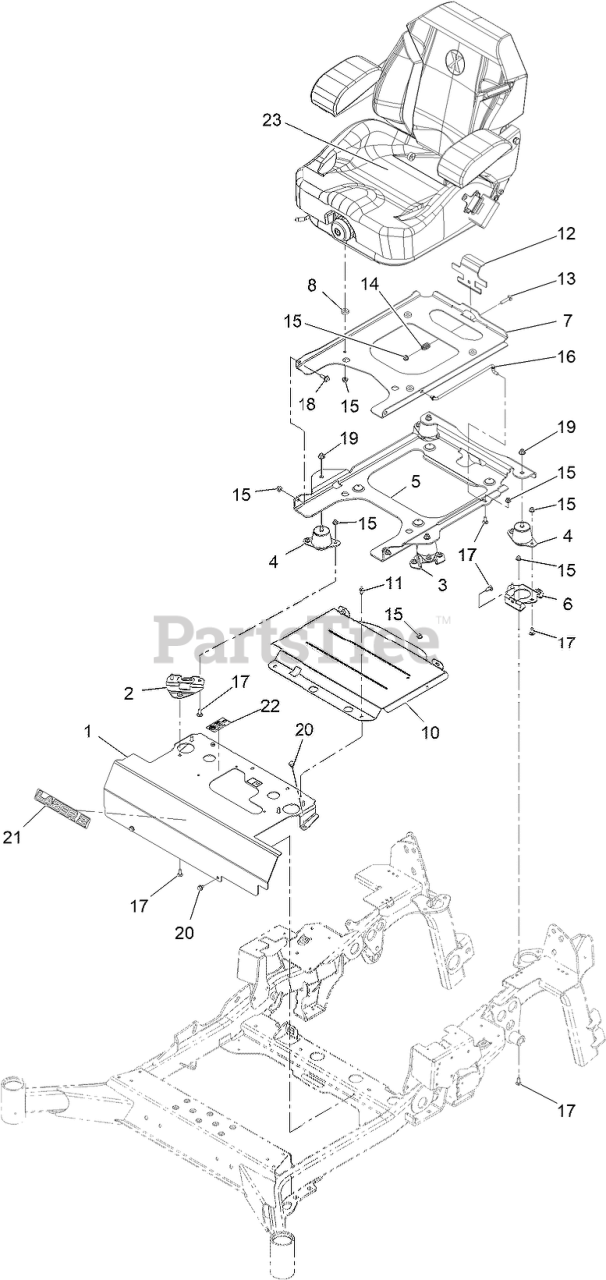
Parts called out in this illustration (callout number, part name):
1	MOUNT-SEAT W/DECALS
2	RISER-SEAT MOUNT, R
3	RISER-SEAT MOUNT, L
4	ISOLATOR-SEAT
5	PLATE,TILT SEAT SUPPORT
6	RISER-SEAT MOUNT, REAR
7	PLATE-FRAME, SEAT
10	HEAT SHIELD - SEAT
11	SCREW-HWH
12	PLATE, SEAT LATCH
13	BOLT-CARR
14	SPRING-COMPRESSION
15	NUT-HF, NI
16	ROD-PROP
17	SCREW-CARR
18	SCREW-SHOULDER
19	NUT-HF, NI
21	DECAL, LAZER MODEL
22	DECAL-TRANS FLUID
23	ASM-SUSPENSION SEAT, EXMARK
